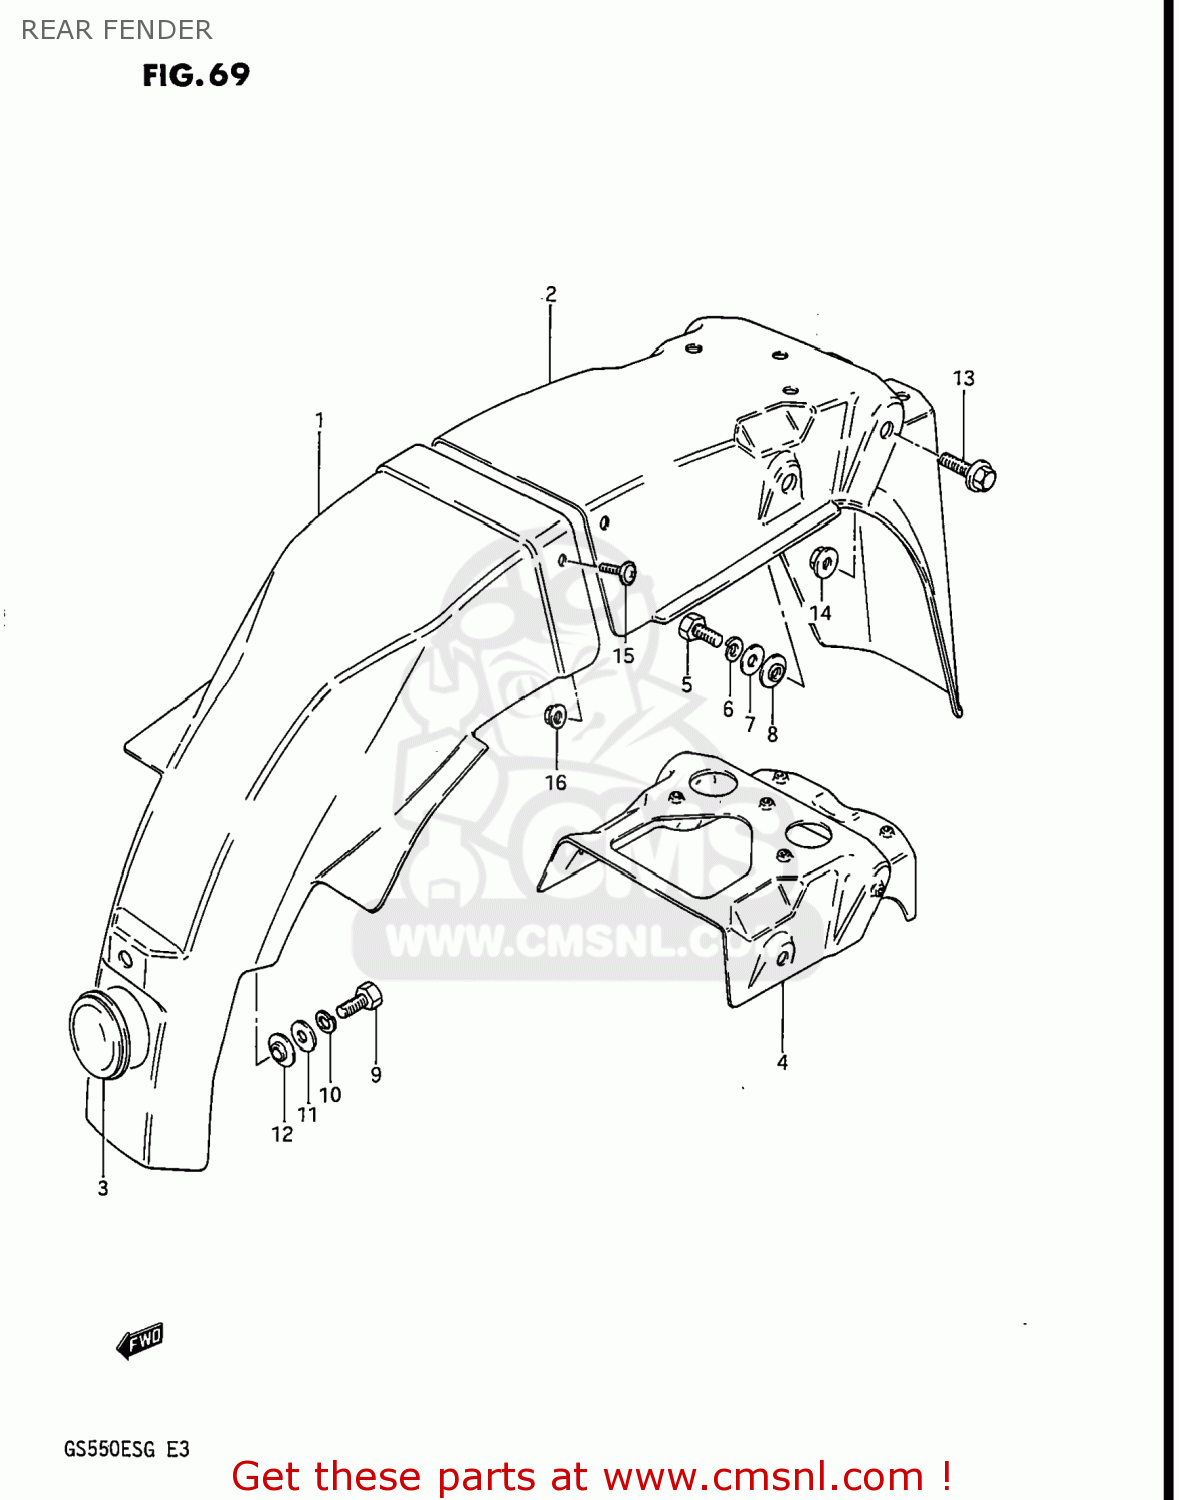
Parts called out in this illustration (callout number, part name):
1	BODY,REAR FENDER,FRONT
2	BODY,RR FENDER RR
3	GROMMET,REAR FENDER,FRONT
4	REINFORCEMENT,REAR
5	BOLT
6	LOCK WASHER
7	WASHER
8	WASHER
9	BOLT, UPPER
10	WASHER,LOCK
11	WASHER 6MM
12	WASHER
13	BOLT
14	NUT
15	SCREW
16	NUT
